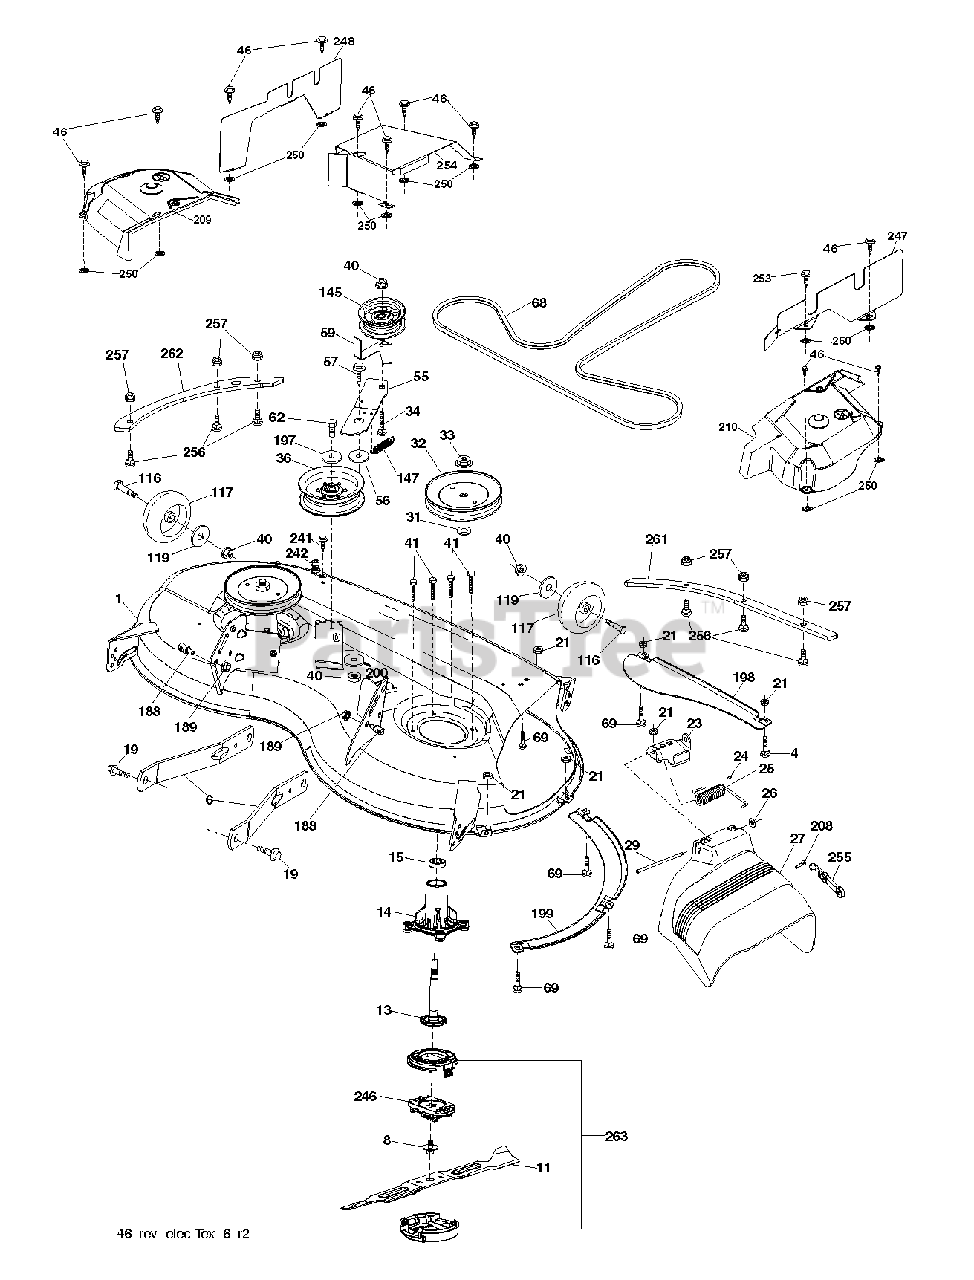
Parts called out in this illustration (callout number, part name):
1	HOUSING 46 WELDMENT TTR X498 G
4	BOLT
6	ARM.SUSPENSION.MOWER.R
8	SCREW.SEMS.7/16-20X1.HEX.HEAD
11	BLADE.REVOLTION.46"BAGER.PT43
13	SHAFT ASM.REV.TALL.N/GREASEBL
14	HOUSING.MANDREL.REV.TALL.N/GRS
19	BOLT.SHOULDER
21	LOCKNUT
23	BRKT.DEFLECTOR.38"2005+
24	CAP-SLEEVE LT
25	SPRING.TORSION.DEFLECT
26	NUT PUSH M
27	SHIELD SUBASM DEFLECTOR 46 FRE
29	ROD.HINGE
31	WASHER.SPACER.MANDREL
32	PULLEY.MANDREL.5.438.PD
33	NUT.FLANGE.LOCK.TOP
34	BOLT.3/8-16X1.50
36	PULLEY.IDLER.2006
40	NUT LOCK FLG 3/8-16 UNC
41	BOLT.HEX.WASHR.HED.313-18X1.19
46	SCREW.1/4-20X5/8
56	SPACER.RETAINER
57	SCREW 3/8-16X1
59	GUARD, BELT
62	BOLT-HEX EAK
68	V-BELT
69	BOLT
116	BOLT.SHOULDER.3/8-16X3-5/8.
117	WHEEL. GUAGE RALLY
119	WASHER
145	PULLEY.IDLER.48"PRIMARY
147	SPRING.MOWER.DRIVE.ELECTRIC
188	STUD.FASTNER.W/ANTI-ROTATE
189	NUT LOCK HEX FLANGE 5/16-18
197	WASHER
198	BAFFLE CENTER FRONT
199	BAFFLE FRONT RH
200	WASHER.13/32 X 1 X 1/2.11GUARD
208	SCREW 3/8-16X1/2
209	COVER MANDREL LEFT
210	COVER MANDREL RIGHT
241	SCREW.TT.#10-32X.5.3/8.FLANGE
242	PORT.WASHOUT
246	HOLDER BLADE REVOLUTION
247	SHIELD RIGHT
248	SHIELD LEFT
250	PALNUT 1/4
253	SCREW
254	SHIELD ASSEMBLY 46 TEX REAR DE
255	ELASTIC STRAP KIT
256	SCREW.BUTTONHEAD.1/4-20X1
257	NUT T
261	PLATE.REINFORCE.46.BOLT.ONX431
262	PLATE.REINFOR.46.SIDEBOLT.X431
263	CAP.REVOLUTION ASM
